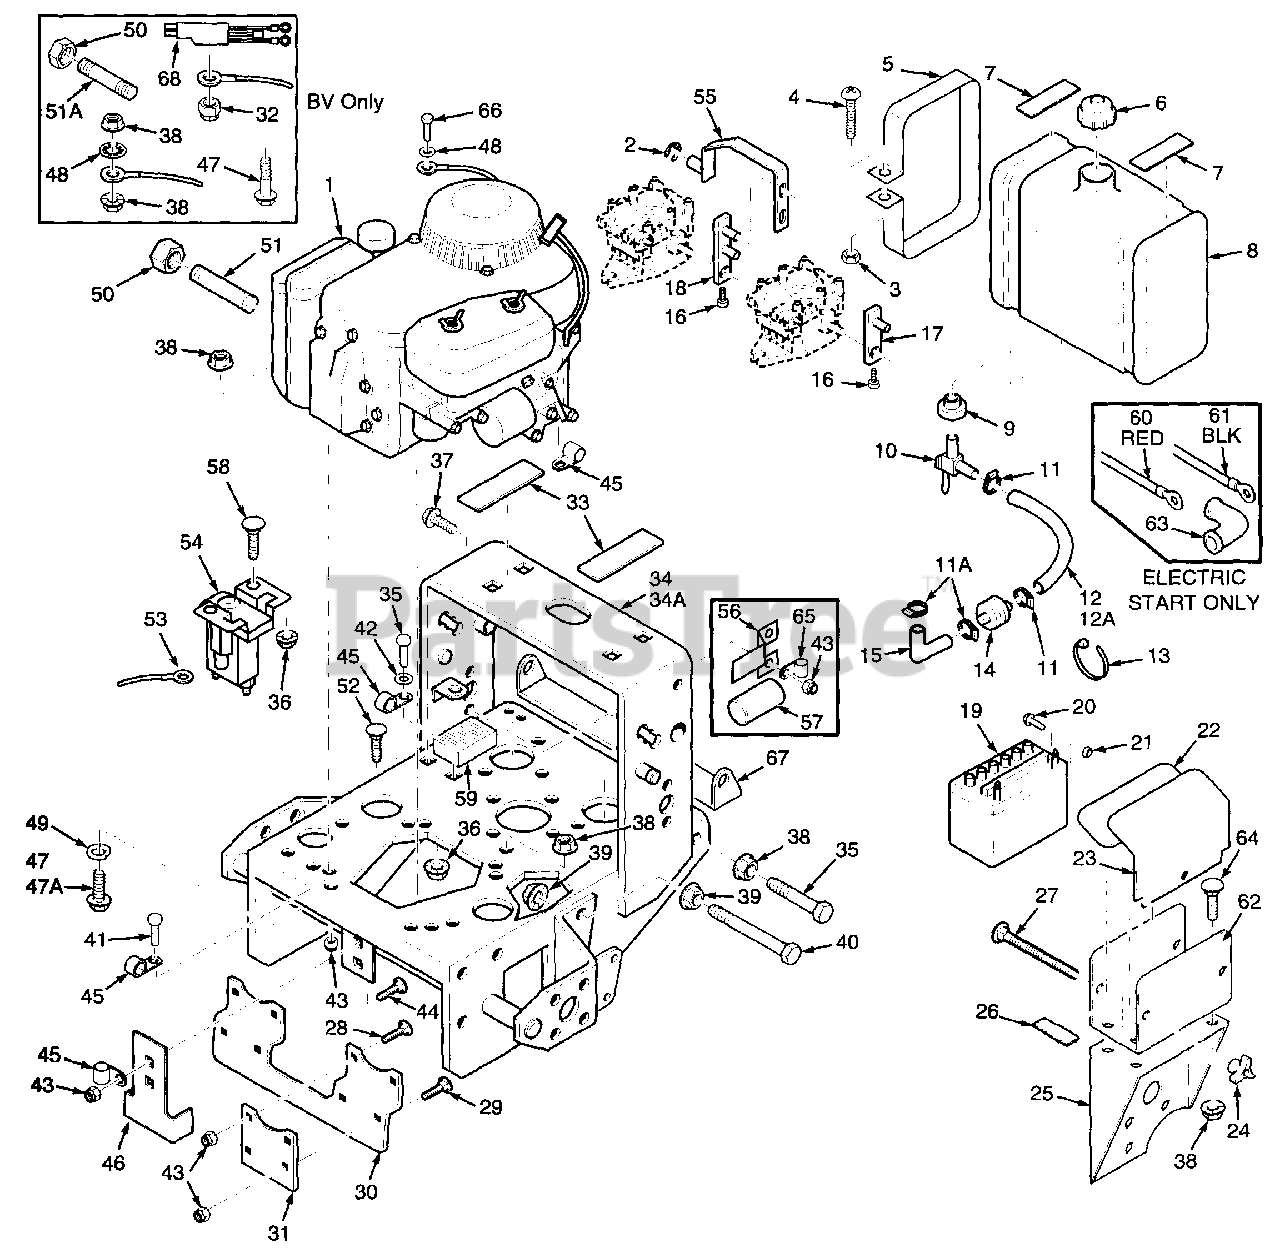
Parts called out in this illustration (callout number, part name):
1	Engine 16BV Briggs Vanguard
2	Retaining Ring, 1/2" Ext. "E"
3	Hex Nut, 1/4-20
4	Screw, 1/4-20 x 2" Rnd. Hd. Phil.
5	Strap, Fuel Tank
6	Cap, Fuel Tank
7	Pad, Rubber - Fuel Tank - Upper
8	Fuel Tank Assy.
9	Bushing
10	Valve, Fuel Shut-off
11	Clamp, Fuel Hose
12	Fuel Hose, 1/4 ID x 20"
13	Cable Tie
16	Capscrew, #10-32 x 1 Soc. Hd.
17	Lever Assy., Pump Control - LH
18	Lever Assy., Pump Control - RH
19	Battery
20	Bolt, 1/4-20 x .50"
21	Nut, 1/4-20
23	Battery Cover
24	Wing Nut, 1/4-20
25	Battery Support
26	Pad, Rubber
27	Bolt, 1/4-20 x 6" Carriage
28	Carriage Bolt, 5/16-18 x 2"
29	Carriage Bolt, 5/16-18 x 1"
30	Stiffener
31	Plate, Backing
32	Nut, 1/4-20 Elastic Stop
33	Pad, Rubber-Fuel Tank, Lower
34	Engine Deck, 16" Wide, W/Decals
34A	Engine Deck, 20" Wide, W/Decals
35	Bolt, 5/16-18 x 1-1/2" Hex Head
36	Nut, 1/4-20 Serrated Flange
37	Capscr., 5/16-18 x 1.25 Sr. Flg.
38	Nut, 5/16-18 Serr. Flange
39	Nut, 3/8-16 Serr. Flange
40	Bolt, 3/8-16 x 2-3/4" Hex Head
41	Hex Head Bolt, 5/16-18 x .75"
42	Flat Washer 1/4"
43	Nut, 5/16-18 Elastic Stop
44	Carriage Bolt, 5/16-18 x 1"
46	Clutch Bracket
47	Capscr, 5/16-18 x 1.50" Sr. Flg.
48	Lock Washer, 5/16 Int. Tooth
50	Pipe Cap
51A	Pipe, 5.25 Nipple
53	Starter Cable, 18" Red
54	Solenoid
55	Shaft Weldment, RH Pump Cntl.
58	Carriage Bolt, 1/4-20 x 3/4"
60	Battery Cable, 31.5" Red
61	Battery Cable, 36" Black
62	Battery Box
63	Rubber Boot
64	Carriage Bolt, 5/16-18 x .75
65	Cable Clamp, .75 ID
67	Pulley Guard, 20" Frame
68	Wire Hrns. Adapter, Man. Start
